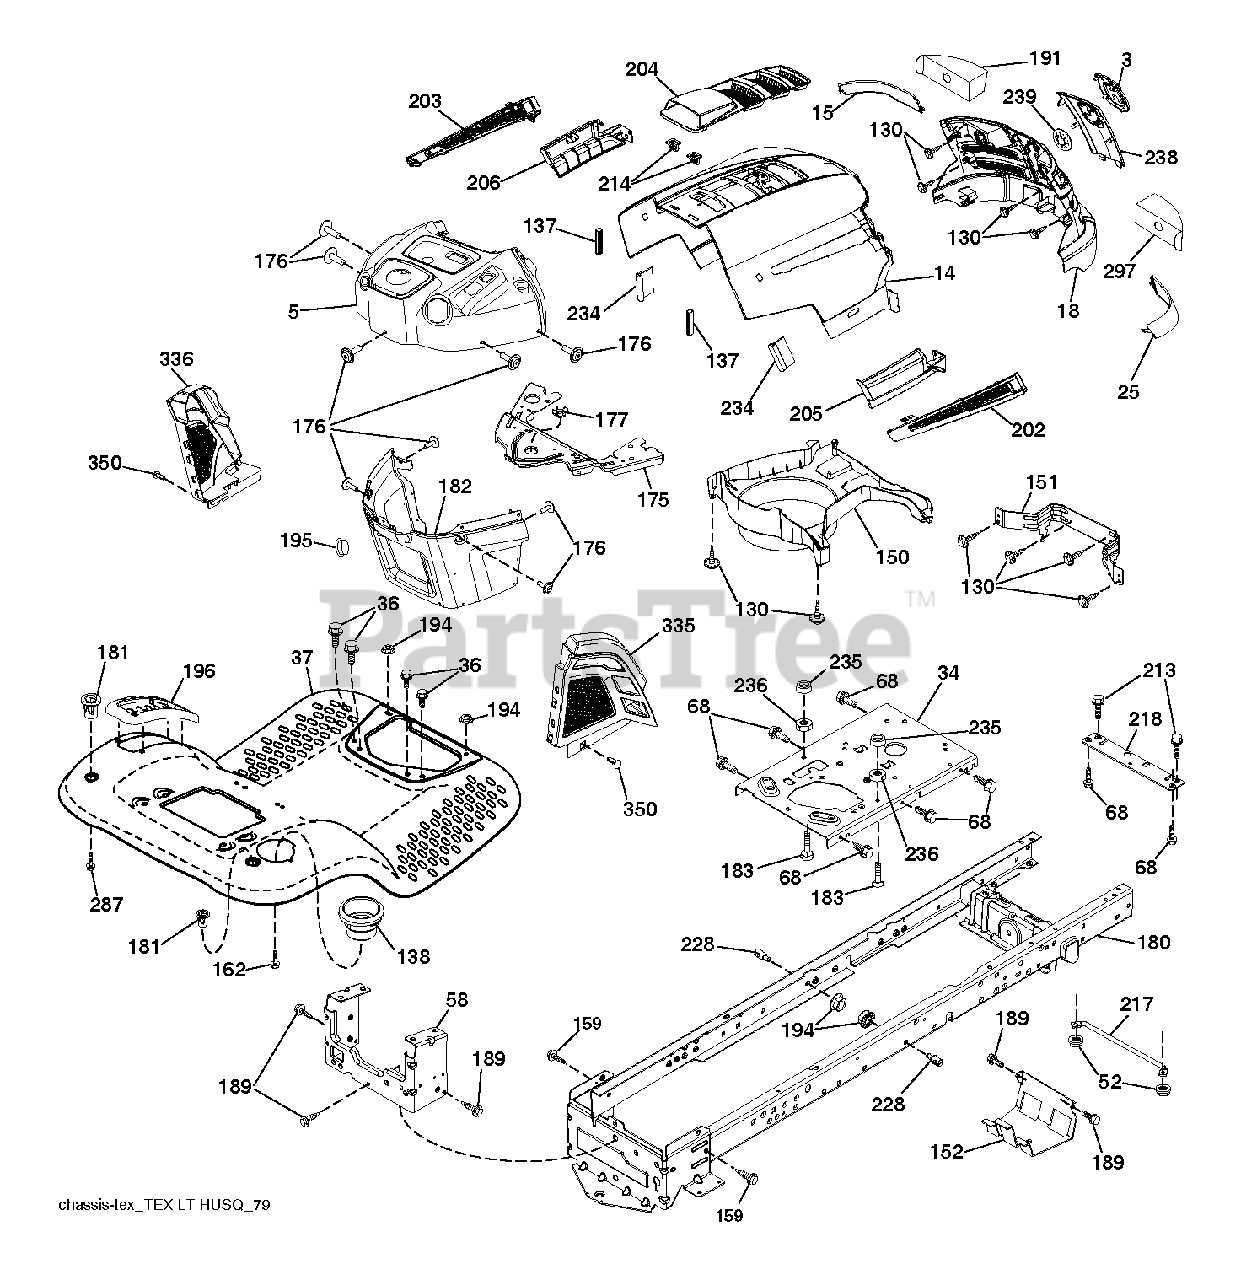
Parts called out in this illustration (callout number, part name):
3	LOGO.HUSQ.GT.LT.CROWN.H
5	SUBASM.DASH.UPPER.W/BUMPER
14	HOOD.HUSQVARNA.LT.ORANGE
15	LENS RH
18	GRILLE.SVC.HUSQVARNA.GREY
25	LENS LH
34	PLATE.ENGINE.WELDED.CHASSIS
36	SCREW 5/16"
37	FENDER.TLT.PDL.CNTRL.W/CPH.ORG
52	LOCKNUT
58	DRAWBAR UPPER 2PC SMALL FENDER
68	SCREW LT
130	SCREW.#10 X 0.750.BOS
137	BUMPER DASH
138	HOLDER.CUP.LT.GREY
151	BRACKET PIVOT
152	SHIELD.BROWNING.W/TEX
159	SCREW, 3/8-16X3/4
162	SCREW.HI-LO.CONSOLE
175	CROSSMEMBER
176	SCREW.#10-24X5/8.RN.QU
177	BUSHING STEERING
180	CHASS.WLDMNT.TL.12GA/2P.48/54
181	BUSHING.MNT.FEND.CRGO.TEX.49
182	DASH.LOWER.PREDATOR LT
183	BOLT.5/16-18X1-1/4 FULL THD
189	SCREW
191	INSERT.REFLECTIVE.RH.
194	NUT LOCK HEX FLANGE 5/16-18
195	PLUG.TEX.DASH.SVC.MINDER.GREY
196	DECKLFT.CONSOL FULL ASSM GREY
202	VENT.SIDE.HUSQVARNA.LT.RT
203	VENT.SIDE.HUSQVARNA.LT.LFT
204	SUBASM.TOP.VENT.HUSQ.LT
205	SKIRT.SIDE.HUSQVARNA.LT.RT
206	SKIRT.SIDE.HUSQVARNA.LT.LEFT
213	BOLT
214	CLIP.RETAINER.TINNER.
217	ROD.PIVOT.HOOD
218	X-PIECE.HOOD.STOP.NON/
228	STUD.FASTNER.W/ANTI-ROTATE
234	BUMPER.HOOD.TEX.HUSQVARNA
235	SPACER FENDER
236	NUT.CENTERLOCK.5/16-
238	TRIM.HUSQ LT.668
287	SCREW 1/4X20
297	INSERT REFLECTIVE
335	COVER.LOWER.DASH.RH.BLACK
336	COVER-LH.LOWER.DASH.GT2.BLACK
350	CLIP.X-MAS.TREE
